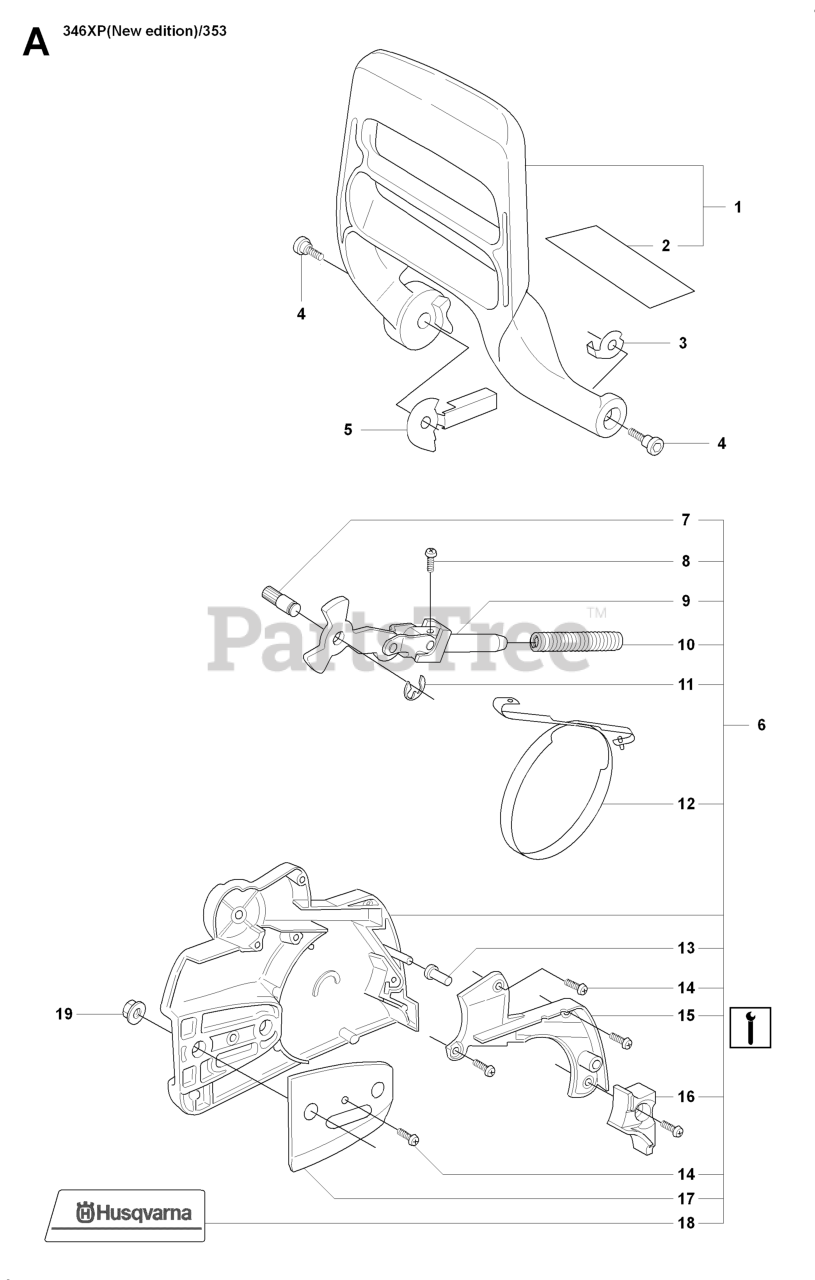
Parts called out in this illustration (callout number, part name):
1	CHAINBRAKE HANDLE
2	PROTECTOR
4	SCREW
6	CHAIN BRAKE SILVER
6	CHAIN BRAKE
12	BRAKE BAND
19	NUT M8 FLANGE
